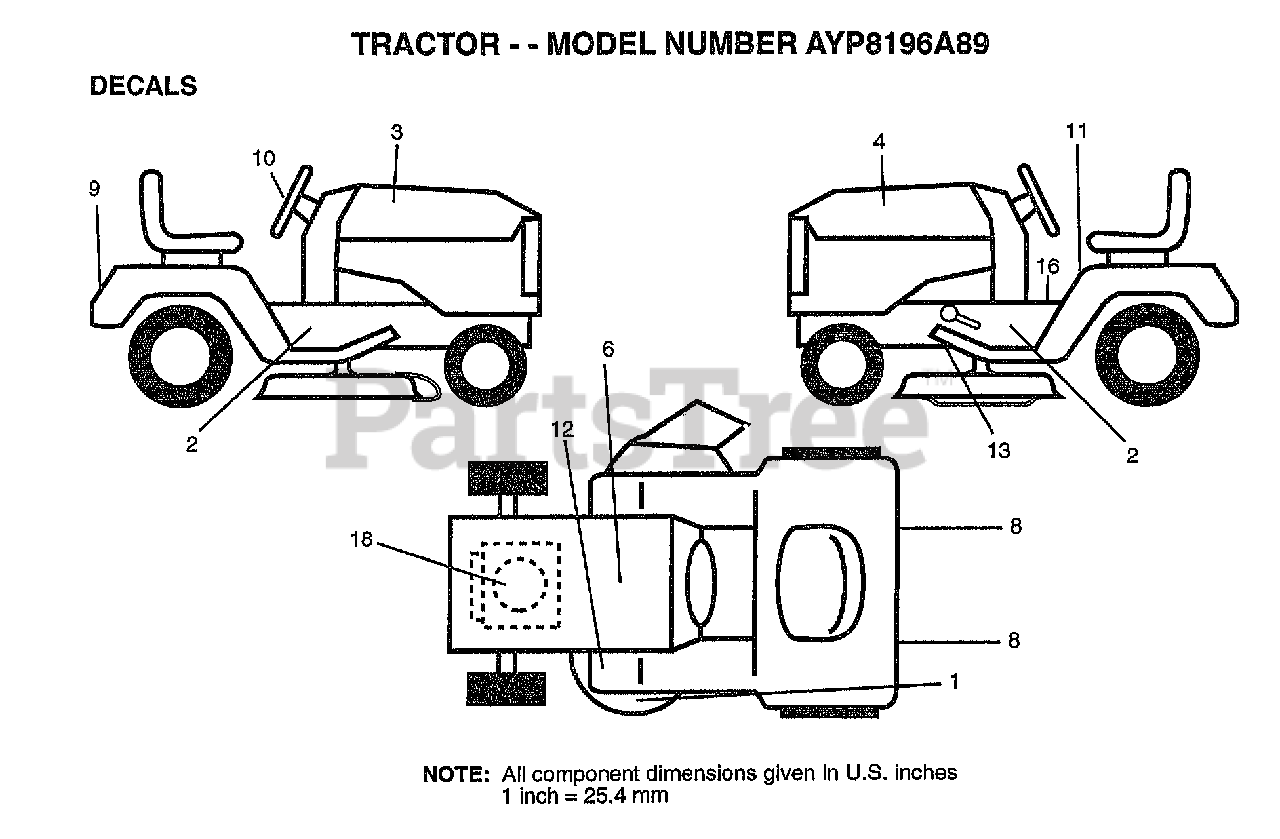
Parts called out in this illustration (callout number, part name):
1	DECAL DECK WIZ +
2	"DECAL CHASSIS 46"""
3	DECAL.HOOD.RH
4	DECAL.HOOD.LH
6	DECAL.BATRY.3-3908
8	REFLECTOR-TAIL YT
10	DECAL.INS.STRG.WL
11	"DECAL DANGER,FEND"
13	"DECAL.V.BELT.44"""
16	"DECAL DASH,OPER."
18	DECAL HP ENGINE
